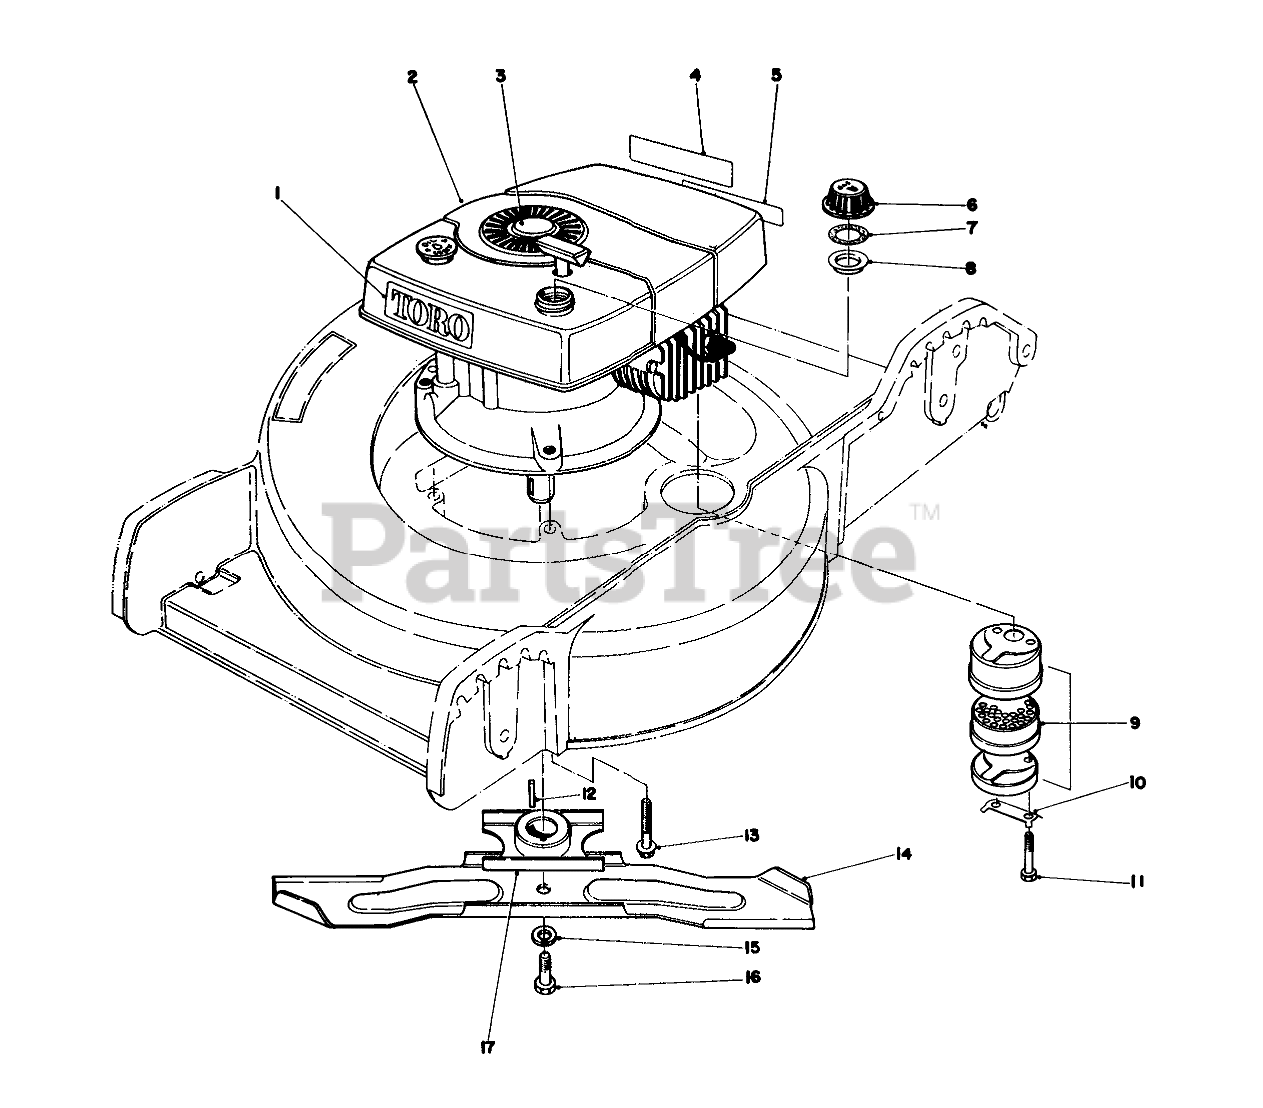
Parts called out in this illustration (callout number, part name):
1	Decal Toro
2	Engine
3	Plug Button
4	Decal Maintenance
5	Decal-Primer Bulb
6	Gas Cap (Incl. Ref. #7 & 8)
7	GASKET
8	GAS CAP BAFFLE
9	Muffler Assy. (Incl. Ref. #10 & 11)
10	CLIP - LOCKING
11	SCREW-HH
12	KEY-SQUARE
13	3/8-16 X 2 CAPSCREW
14	Blade
15	WASHER-LOCK
16	SPECIAL SCREW
17	Blade Retailer
